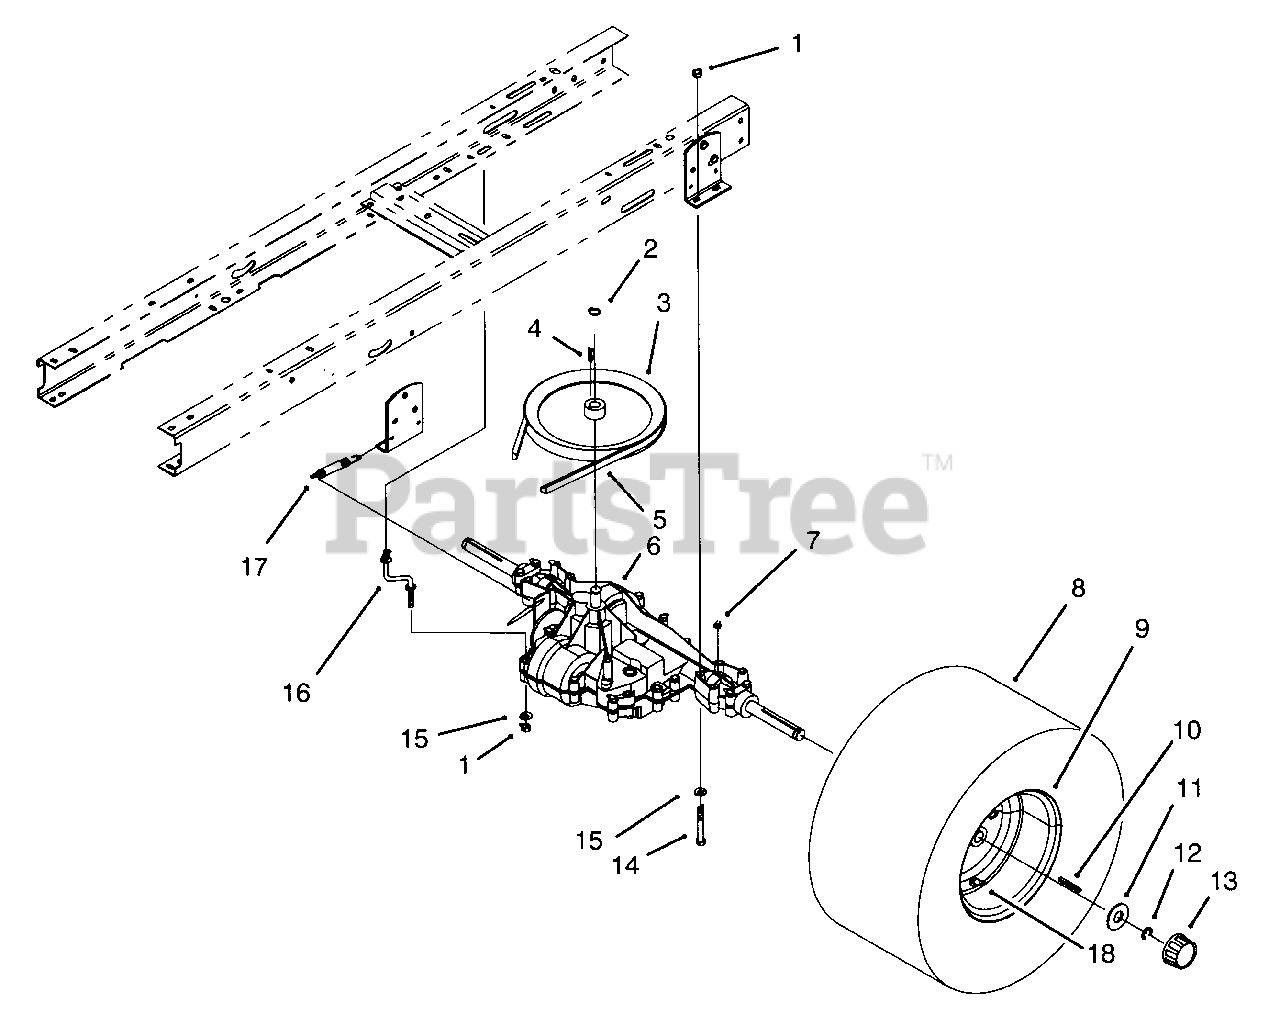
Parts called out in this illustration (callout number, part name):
1	Nut-Lock
2	Ring-Snap
3	Pulley-Transmission
4	Key-Woodruff
5	V-Belt-Traction (Model No. 81140 Only)
6	Transaxle
7	Fitting-Grease
8	Tire (Model No. 81140 Only)
9	Rim (Model No. 81140 Only
10	Key-Square
14	Screw-Hex Hd. Cap
15	Washer-Flat
16	Strap-Torque
17	Spring-Brake Return
18	Valve Stem w/Cap
